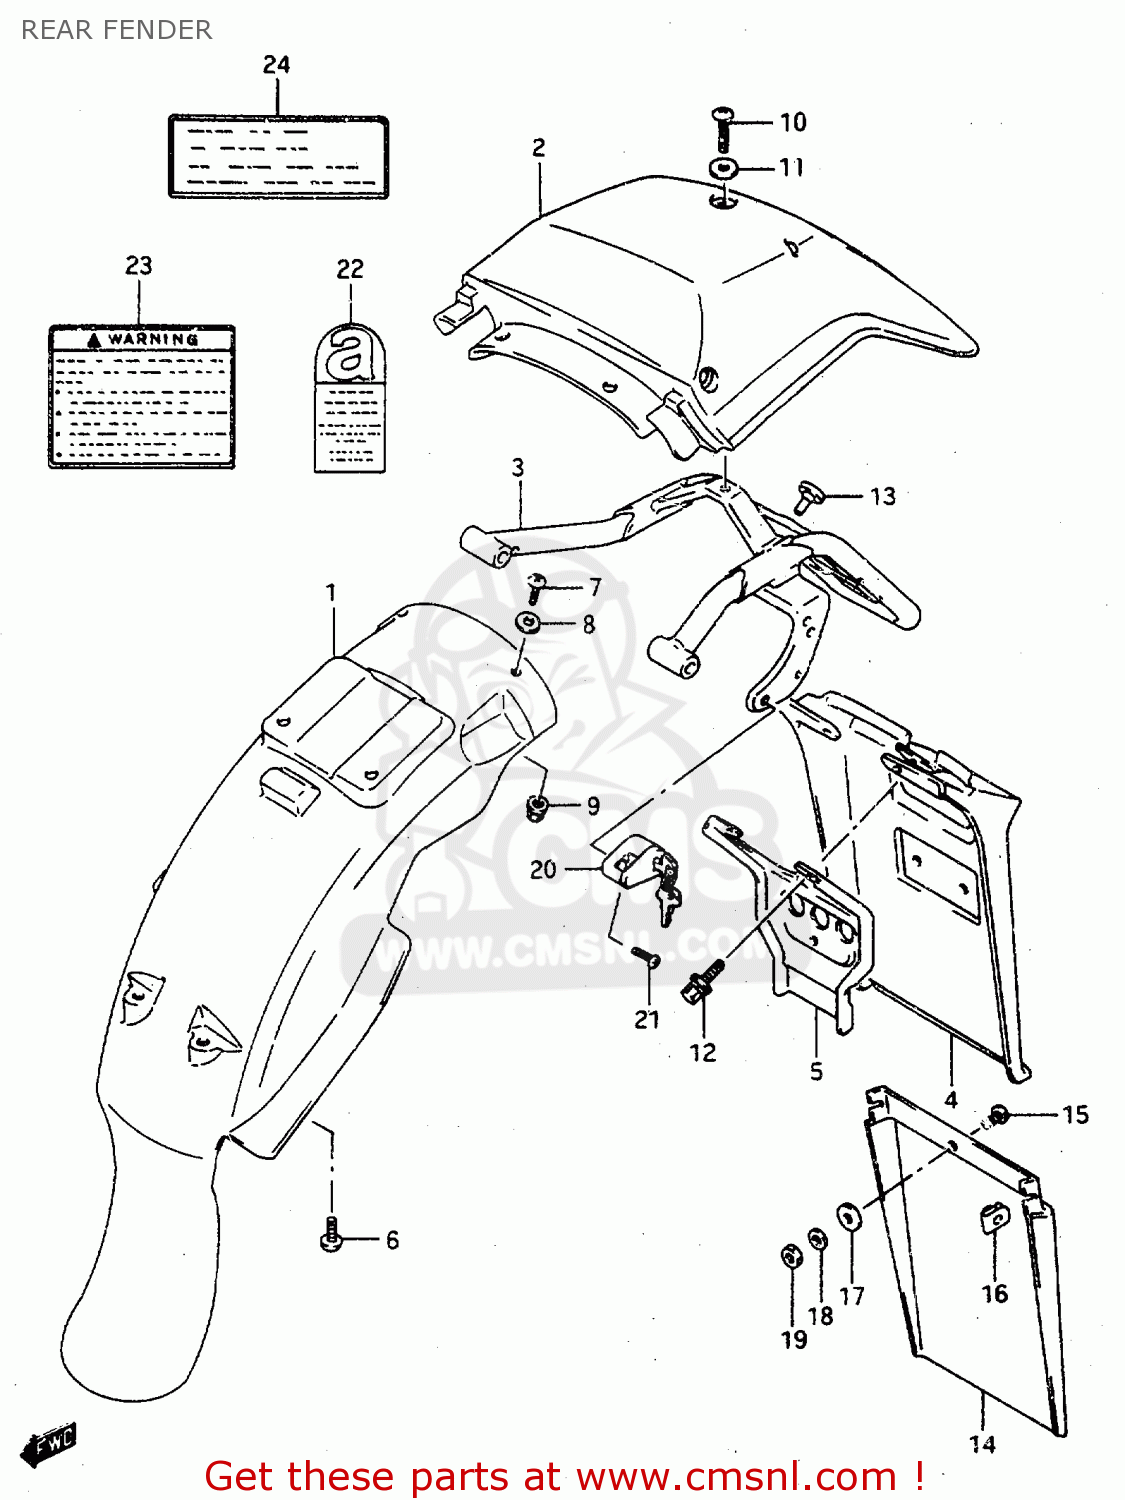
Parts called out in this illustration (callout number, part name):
1	BODY,RR FENDER FR
2	BODY,RR FENDER RR
3	REINFORCEMENT,RR FENDER
4	EXTENSION,RR FENDER
5	REINFORCMENT,REAR FENDER
6	SCREW(6X16)
7	SCREW 6X12
8	WASHER(6.5X18X1)
9	NUT
10	SCREW(6X25)
11	WASHER (6.5X18X2)
12	BOLT
13	CUSHION
14	MUDGUARD,RR FENDER RR
15	SCREW, LOWER
16	NUT
17	WASHER
18	LOCK WASHER
19	NUT
20	LOCK SET,HELMET
21	SCREW
22	LABEL,ASBESTOS WARNING
23	LABEL, WARNING
24	LABEL,CAUTION
25	LABEL, TIRE AIR PRESSURE
26	MANUAL, OWNER'S
